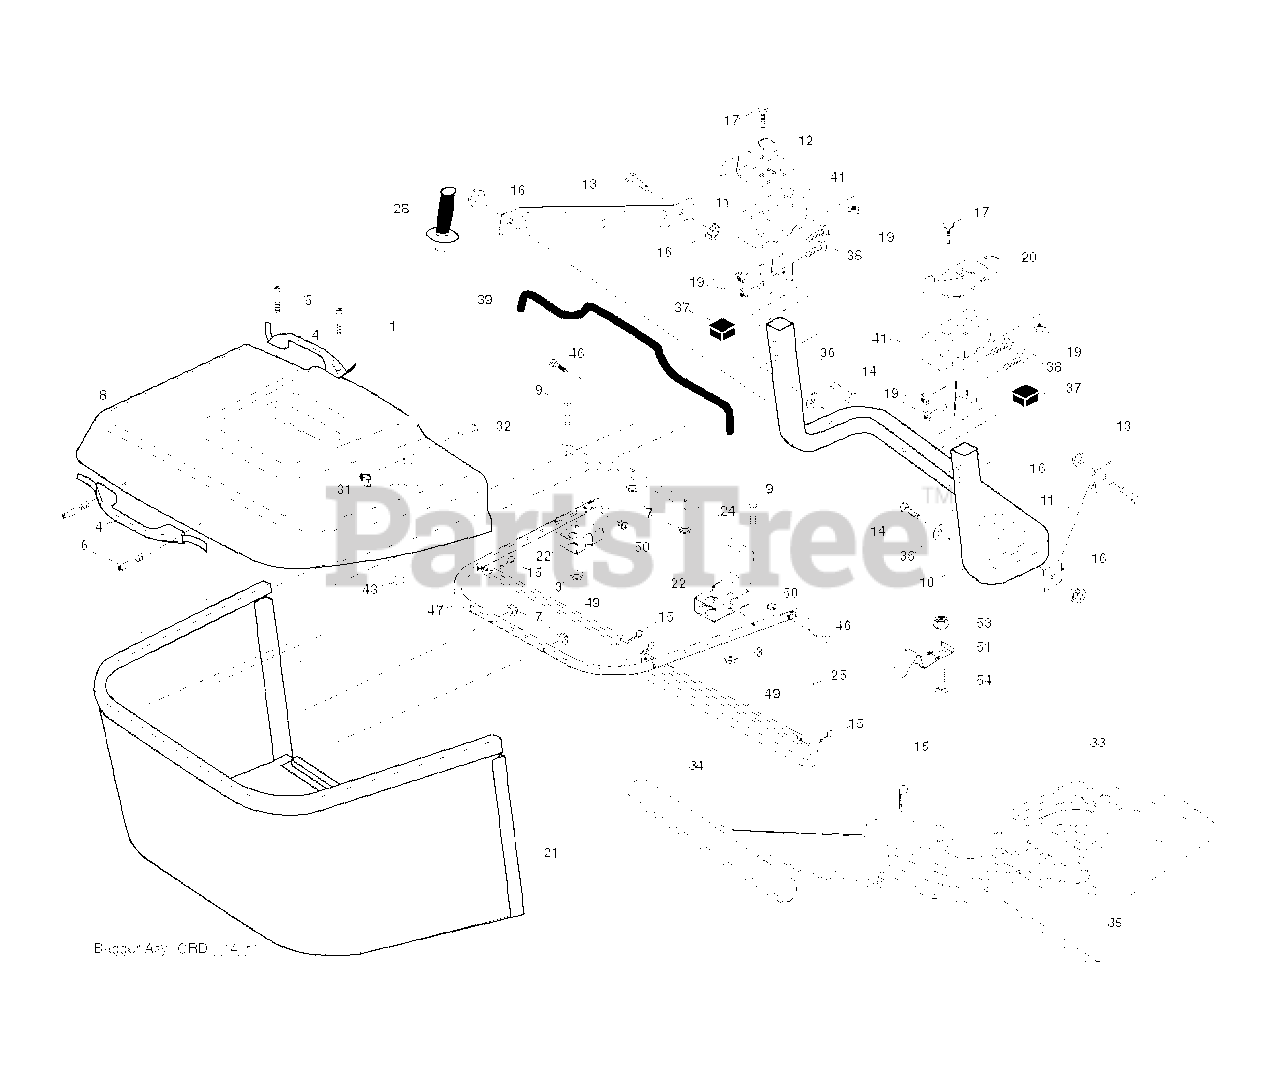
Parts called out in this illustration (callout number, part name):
1	TUBE.PNT.HDL.BAGGER.
3	NUT T
5	SCREW.PAN.HEAD
8	BAGGER.COVER.SEAL.ASM.CRD.428
11	BRACKET
14	BOLT-HEX EAK
15	RETAINER-SPRNG RB
16	NUT LOCK FLG 3/8-16 UNC
17	BOLT
19	NUT LOCK HEX FLANGE 5/16-18
20	BRKT.PIVOT.RH.CRD
21	BAGGER.ASM.CRD.2007
22	BRACKET.BAGGER.SD.
24	TUBE
28	GRIP.HANDLE.BLACK
31	RETAINER CLIP
32	RIVET,DRILLED
33	MULCHING.PLUG.1078.CRD.NON-TEX
35	PIN
38	BOLT.5/16-18X2.5
39	SEAL.BAGGER.CRD
41	BRACKET.BAGGER.SD.
43	PLUG, TUBING END
46	BOLT.CARRIAGE.5/16-18
50	NUT.71038.31-18.HEX.NYLOCK
53	NUT
54	BOLT
